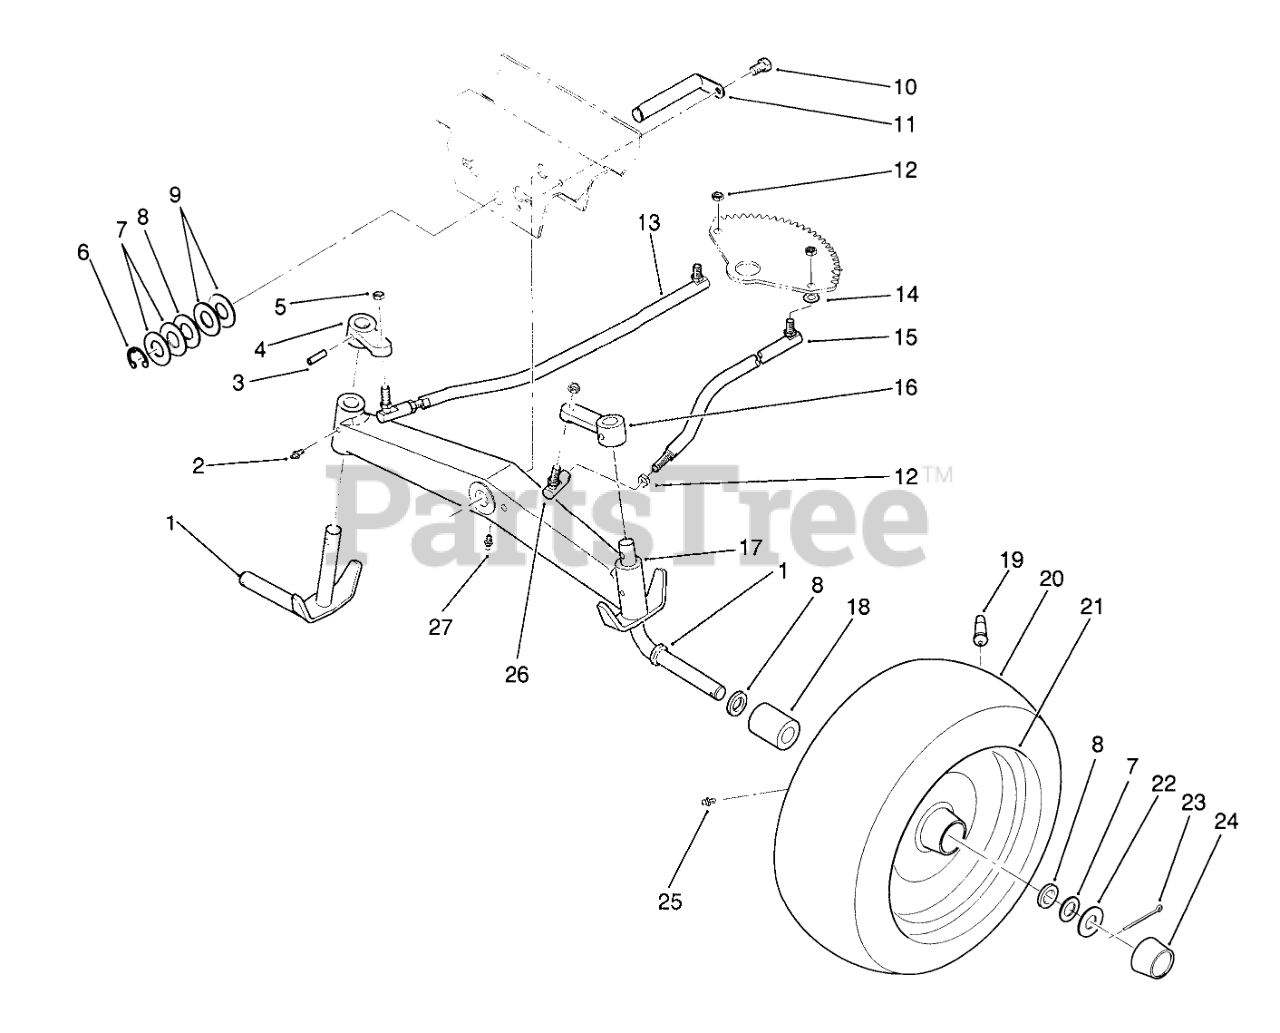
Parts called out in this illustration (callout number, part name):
1	Spindle-W.A.
2	Fitting-Grease
4	Arm-Spindle, R.H.
5	Nut
6	E-RING
7	WASHER-SHIM
8	WASHER
9	WASHER
10	Bolt
11	WLDMT-AXLE PIN R
12	NUT-6
13	Ball Link ASM
14	Collar
15	Ball Link ASM
16	Arm-Spindle, L.H.
17	Axle-Front
18	BEARING-WHEEL
19	VALVE
20	Tire (16 x 6.5-8) 2-Ply -2 Wheel Axel
21	Wheel
22	WASHER WHEEL
23	COTTER PIN-4
24	HUBCAP
25	ZERK-GREASE
26	BALL-JOINT
27	FITTING-GREASE
